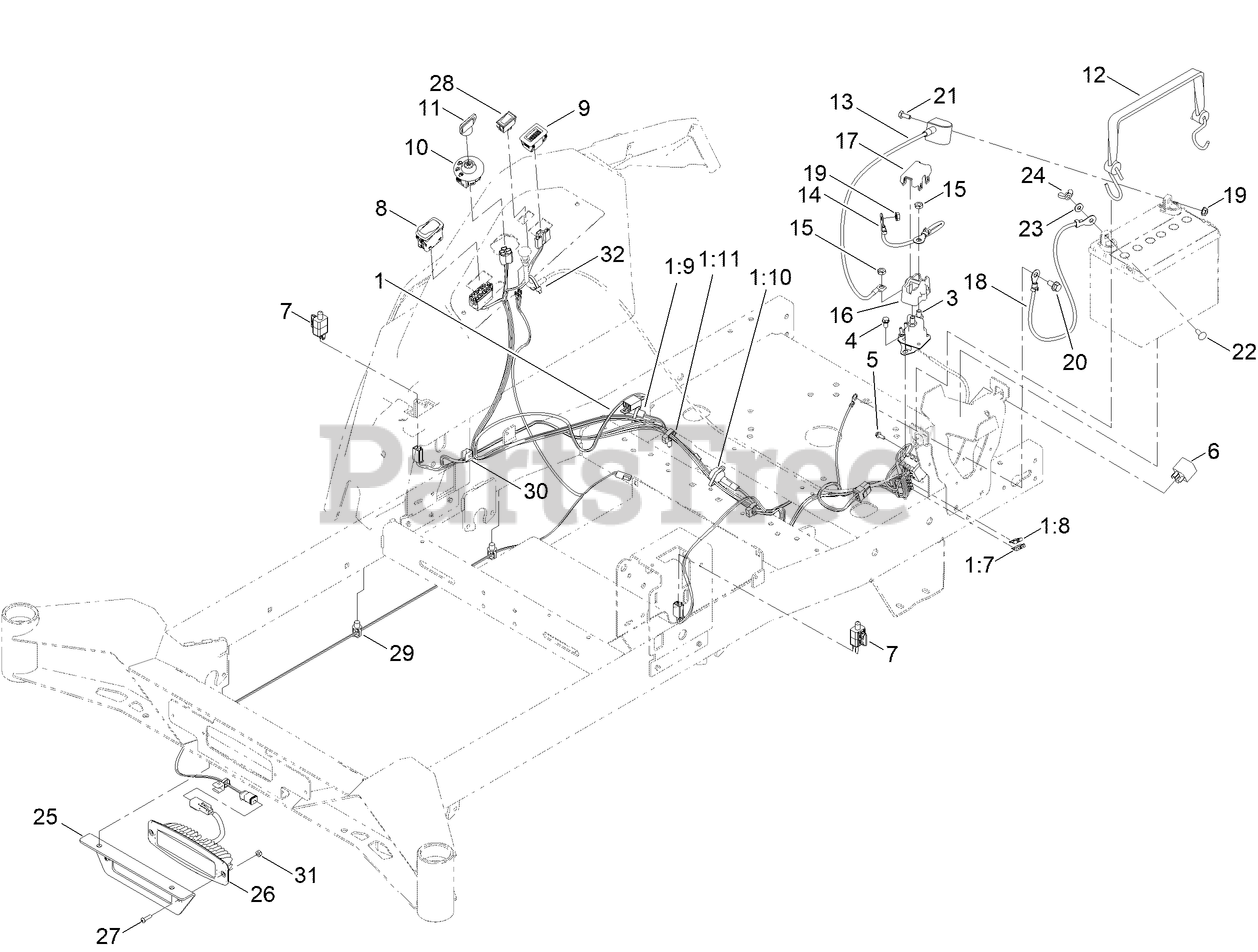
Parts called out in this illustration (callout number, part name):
1	HARNESS-WIRE, MAIN
1:7	FUSE-BLADE, 15 AMP
1:8	FUSE-BLADE, 25 AMP
1:9	CAP-OVER MOLD, 1M/1F
1:11	CLIP-TUBING, HARNESS
3	SOLENOID
4	SCREW-HWH
5	SCREW-TAPTITE
7	SWITCH
8	SWITCH-ROCKER, ON-NONE-ON
9	HOUR METER
10	SWITCH-IGNITION
11	KEY-IGNITION
12	STRAP-RUBBER
13	CABLE-BATTERY,RED
14	CABLE-BATTERY, POSITIVE
15	NUT-HJ
16	COVER-SOLENOID
17	CAP-SOLENOID
18	CABLE-BATTERY, BLACK
19	NUT-HF
20	SCREW-HHF
21	SCREW-HH
22	BOLT-CARR
23	WASHER
24	NUT-WING
25	BRACKET-MOUNTING, LIGHT
26	MOUNT-FLUSH, LIGHT
27	SCREW-HSBH
28	SWITCH-ROCKER
29	HARNESS-WIRE, LIGHT HARNESS
30	CLIP-EDGE W/TIE, PERPENDICULAR
31	NUT-LOCK, NI
32	TIE-CABLE
